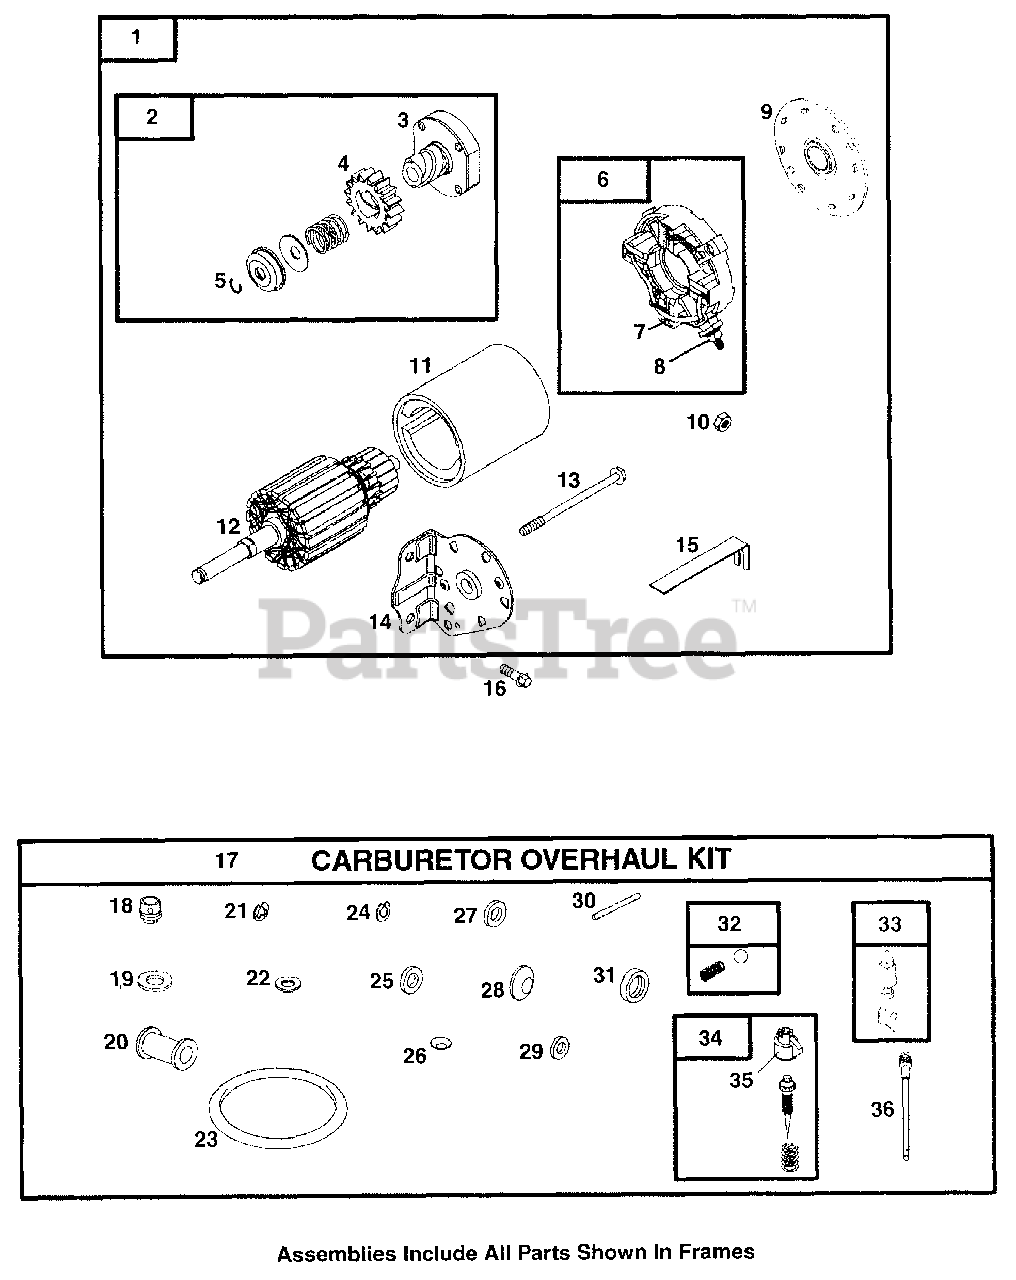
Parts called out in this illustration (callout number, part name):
1	Starter Motor
2	Starter Drive
3	Drive Clutch
4	Pinion Gear
5	Retaining Ring
6	Brush Retainer
8	Nut (Brush Retainer)
10	Nut (Brush Retainer)
11	Starter Housing
12	Armature
13	Bolt (Starter Motor)
14	Drive Cap
15	Starter Strap
16	Screw (Drive Cap)
17	Carburetor Kit
19	Sealing Washer (Float Bowl)
20	Throttle Spacer
21	E Ring Retainer
22	Sealing Washer (Carburetor Plug)
23	Float Bowl Gasket
24	Retaining Ring
26	Welch Plug
28	Welch Plug
29	Choke Shaft Seal
30	Float Hinge Pin
31	Throttle Shaft Seal
32	Choke Ball Locator
33	Float Needle Valve
34	Idle Mixture Valve
35	Limiter Cap
